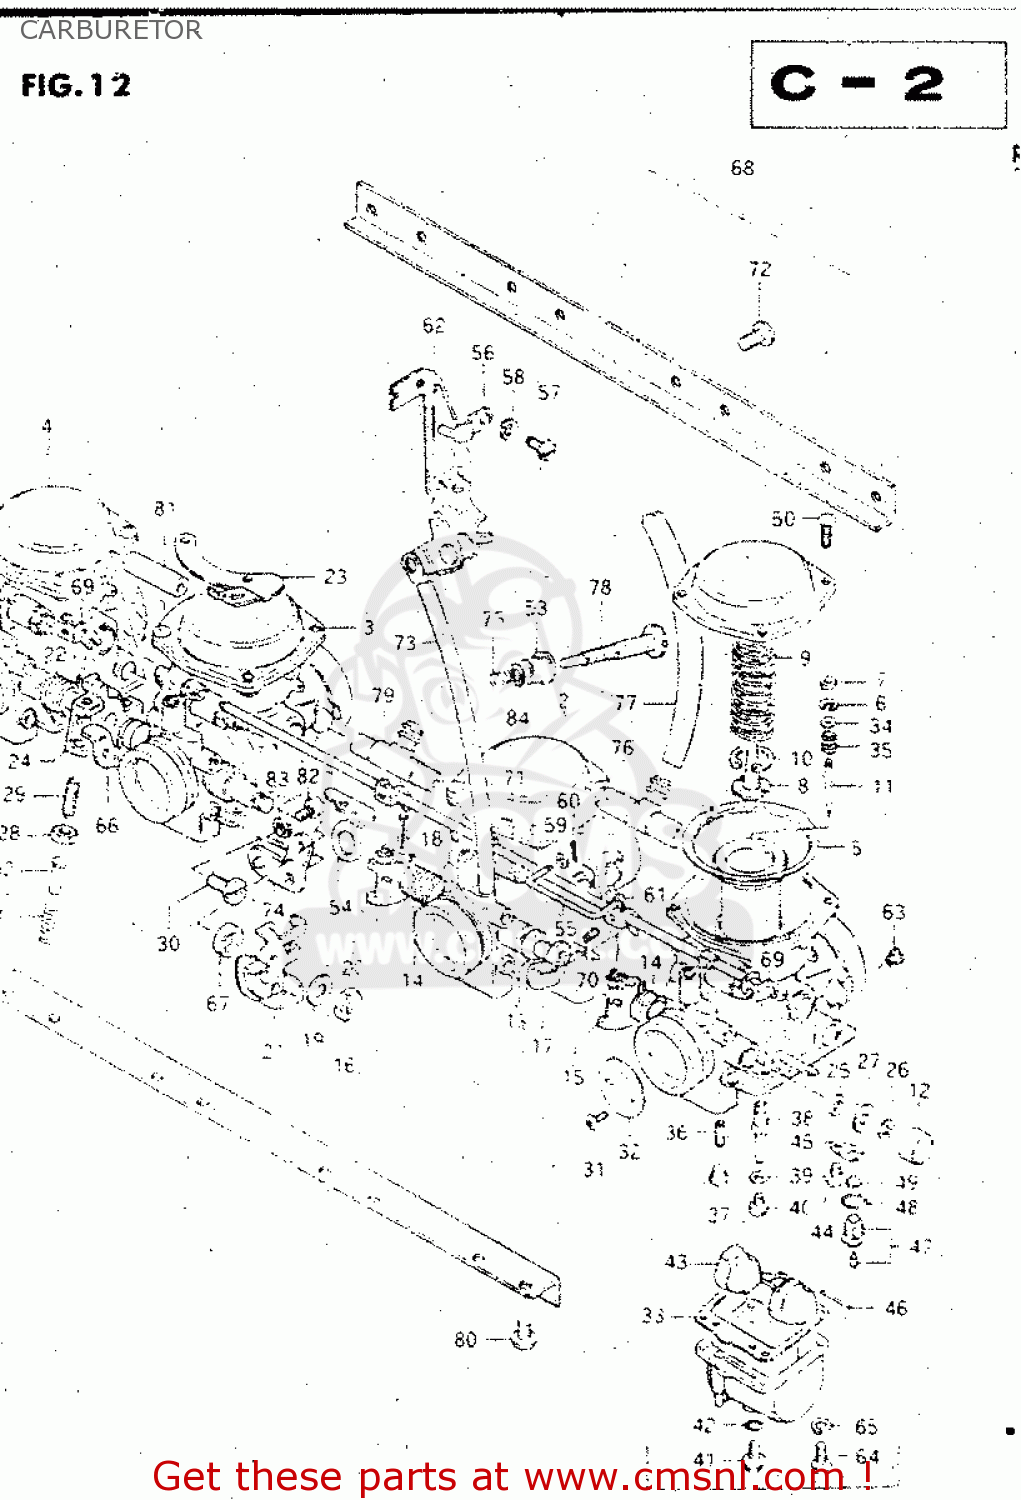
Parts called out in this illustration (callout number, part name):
1	CARBURETOR ASSY, LH
2	CARBURETOR ASSY, ML
3	CARBURETOR ASSY, MR
4	CARBURETOR ASSY, RH
5	DIAPHRAGM ASSEMBLY
6	CLIP,NEEDLE
7	RING
8	HOLDER,GUIDE
9	SPRING
10	E RING
11	NEEDLE, JET (5F42-3)
12	CAP
13	GASKET,THROTTLE SHAFT (NAS)
14	SPRING,THROTTLE SHAFT
15	SHAFT,THROTTLE
16	NUT 8MM
17	SHAFT,THROTTLE
18	PIN,THROTTLE SHAFT
19	WASHER
20	LEVER,THROTTLE SHAFT
21	LEVER ASSEMBLY,THROTTLE
22	SPRING,THROTTLE SHAFT
23	BRACKET
24	SHAFT,THROTTLE
25	SEAL
26	E RING
27	GASKET,THROTTLE SHAFT (NAS)
28	NUT
29	SCREW
30	SCREW
31	SCREW
32	VALVE,THROTTLE (BUTTERFLY)
33	GASKET,FLOAT CHAMBER (NAS)
34	WASHER
35	SPRING
36	JET
37	PLUG,NEEDLE JET
38	JET, NEEDLE (X-6)
39	WASHER,NEEDLE NOZZLE
40	JET
41	PLUG,DRAIN
42	GASKET (NAS)
43	FLOAT
44	SCREW 4X6
45	PLATE,NEEDLE VALVE FITING
46	PIN,FLOAT
47	VALVE ASSEMBLY,NEEDLE
48	O-RING,NEEDLE VALVE
49	FILTER
50	SCREW
51	SPRING,THROTTLE SCREW
52	PIN
53	BUSH
54	BRACKET,THROTTLE ADJUST
55	ROD,STARTER LEVER
56	BRACKET,STARTER
57	BOLT
58	LOCK WASHER
59	SEAT,SPRING
60	PIN
61	LEVER ASSY
62	BRACKET
63	JET,AIR
64	SCREW
65	LOCK WASHER
66	SHAFT,THROTTLE
67	WASHER
68	CARBURETOR ASSEMBLY
69	LEVER
70	SCREW
71	SHAFT,STARTER
72	SCREW
73	HOSE
74	BRACKET,THROTTLE ADJUST
75	SPRING
76	NIPPLE
77	HOSE
78	SCREW
79	NIPPLE,CARBURETOR
80	SCREW 6X12
81	NIPPLE
82	SCREW
83	LOCK WASHER
84	WASHER
